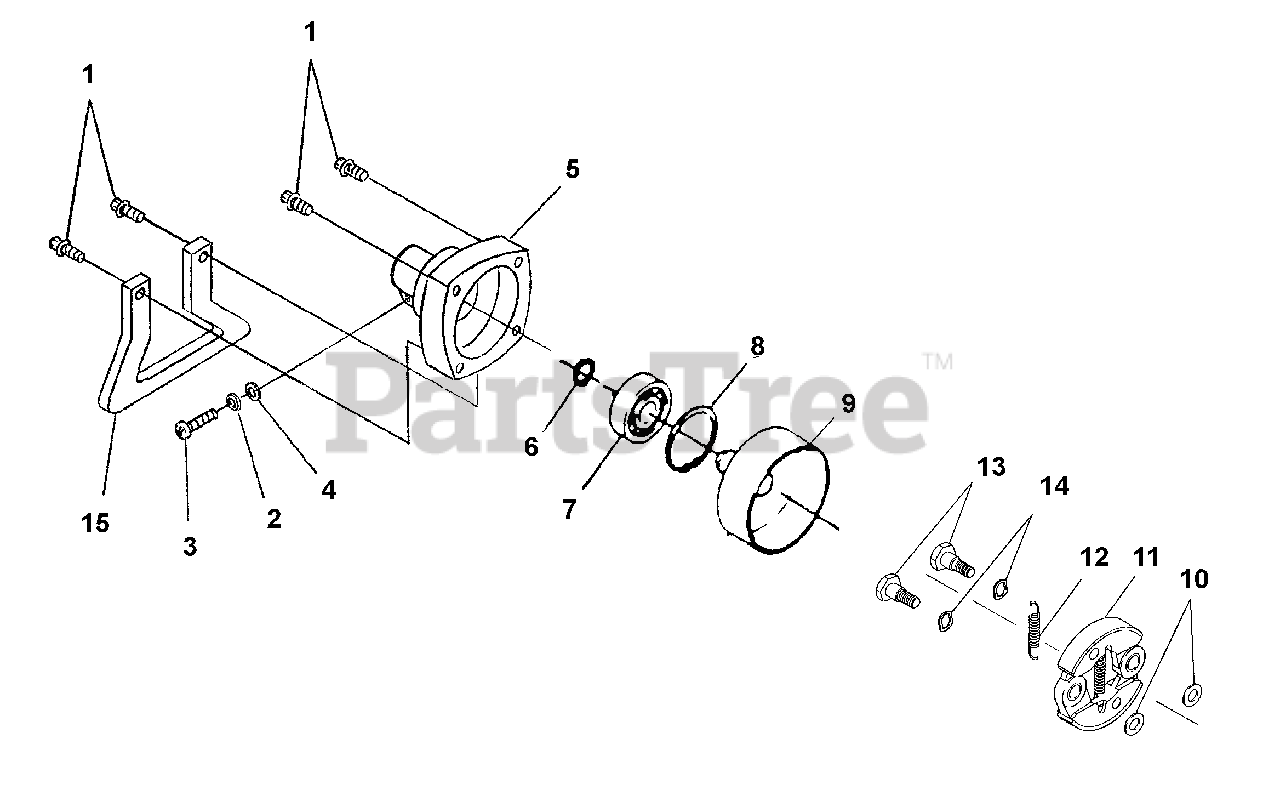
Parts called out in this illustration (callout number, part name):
1	Bolt & Washer
3	Screw
5	Clutch Case
6	Snap Ring
8	Snap Ring
9	Clutch Drum
11	Clutch Shoe Kit
12	Clutch Spring
13	Bolt
15	Stand
